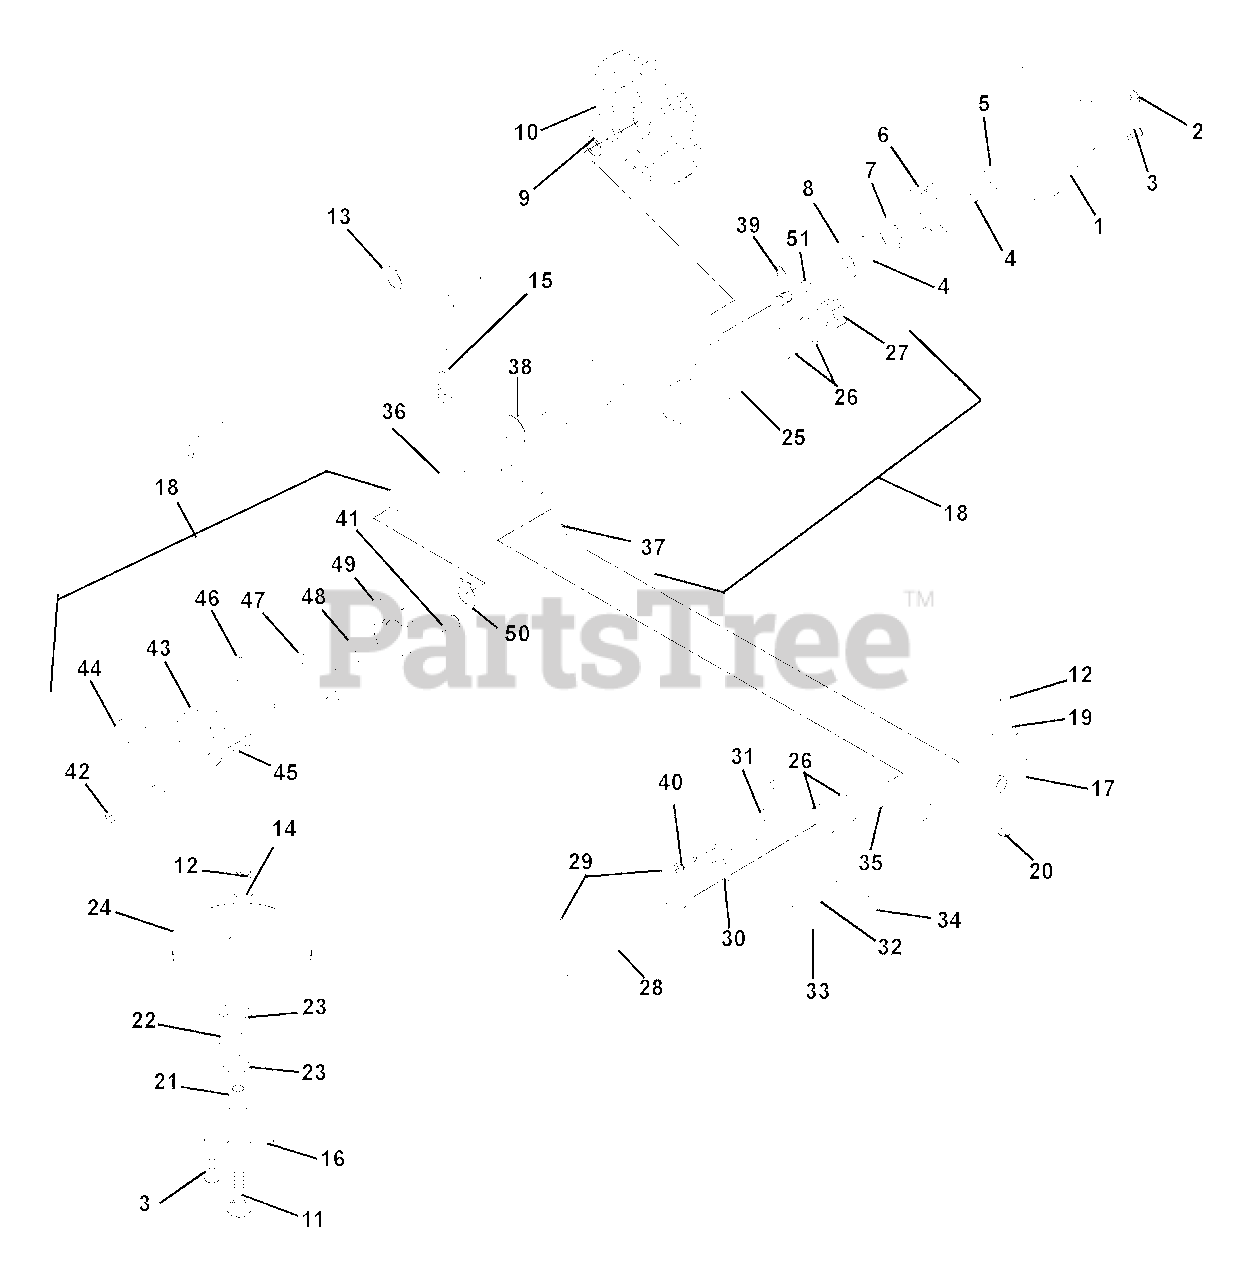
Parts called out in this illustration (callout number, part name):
1	COVER, GEAR
2	RG-RTNG-EXT .438X.035
3	SCR-TAP 12-24X.50 HWH TR YWZC
4	WSHR-FL-STL .52X.827X.062 YWZC
5	WSHR-FL-STL.531X1.00X.063 YWZC
6	IDLER GEAR
7	BRG-BALL .500X1.38X.437
8	RETAINER
9	BRG-BALL .625X1.383X.50
10	DIFFERENTIAL ASSEMBLY
11	BLT-RDHDSQNK .31-18X1.75 G5YZ
12	NUT-LK-CTR .31-18 YWZC
13	RG-RTNG-EXT .579X.035
14	WSHR-FL-STL .328X.87X.179 YWZC
15	SG-TENS .051X.60X2.25 WLD 7.0
16	RETAINER - BEARING
17	PIVOT, CHANNEL WELDMENT
18	KIT, LM DRIVE CARRIER
19	WSHR-FL-STL.344X.688X.065YWZC
20	BLT-RHDSSQNK .31-18X.62 G5YZ
21	SPINDLE - BEARING
22	WSHR-FL-STL 1.062X1.344X.032PL
23	BRG-BALL .625X1.375X.43
24	FRICTION SHEAVE
25	DRIVE CARRIER
26	BRG-BALL .562X1.375X.437
28	SHAFT, HEX
29	PIN-ROLL .188X.88
30	RETAINER PLATE
31	SHIFT ARM WELDMENT
32	SHIFT LINK
33	PIN-ROLL .125X.50
34	PUSH NUT, .25
35	WSHR-FL-STL 1.390X2.00X.020 PL
36	ROD - GUIDE
37	ACTUATOR, WBLM DRIVE
38	BRG-BALL .625X1.383X.50
39	RG-RTNG-EXT .438X.035
40	SCR-TAP 12-24X.50 HWH TR YWZC
41	SCR-TAP 5HX-0.8X16MM H-FL-YWZC
42	NUT-LK-CTR .25-20 YWZC
43	FRICTION WHEEL HUB
44	DISC, FRICTION - 730 MAT'L
45	BLT-HEX .25-20X.50 GR5 YWZC
46	PLATE, BEARING
47	BEARING RETAINER
48	BRG-BALL 1.0X2.0X.56 (1641)
49	BEARING RETAINER
50	RG-RTNG-EXT 1.00X.042
51	IDLER SHAFT
